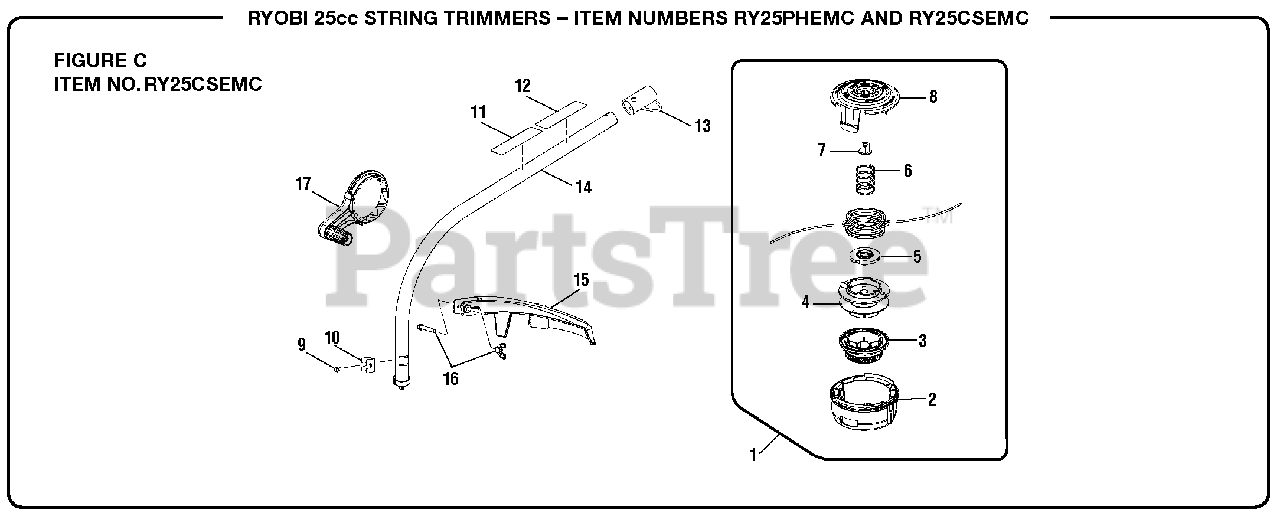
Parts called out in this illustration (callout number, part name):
1	Trimmer Head Assembly (.095)
2	Lower Housing
3	Bump Knob (Green)
5	String Guide
6	Compression Spring
7	Flange Nut (M8)
8	Upper Housing
9	Screw (#10-32 x 3/8 in., Hex Washer Hd. S.T.)
11	Expand-it Label
12	Warning Icon Label
13	Storage Hanger Cap
14	Curved Shaft Assembly
15	Grass Deflector Assembly
16	Fastener Kit
17	Crank Handle Assembly
